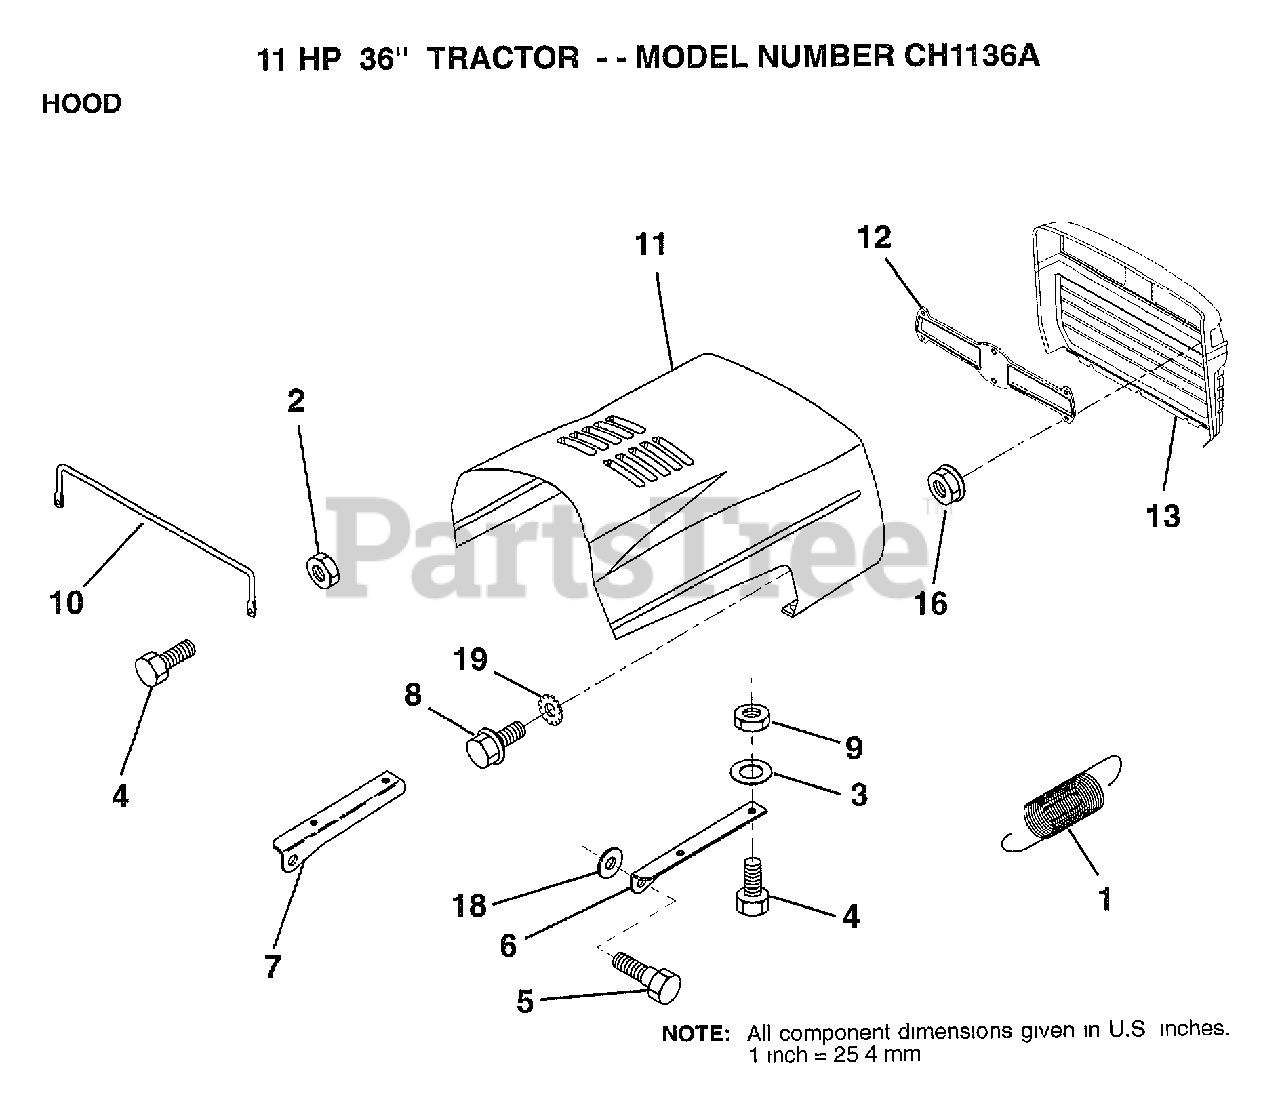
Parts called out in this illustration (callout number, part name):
1	EXT SPRING
2	NUT
3	WASHER
6	BRKT HOOD RH
7	BRKT HOOD LH
9	NUT
10	"BRACE,HOOD"
11	HOOD
13	GRILL (BLACK)
16	NUT
18	WASHER
19	LOCKWASHER GT
